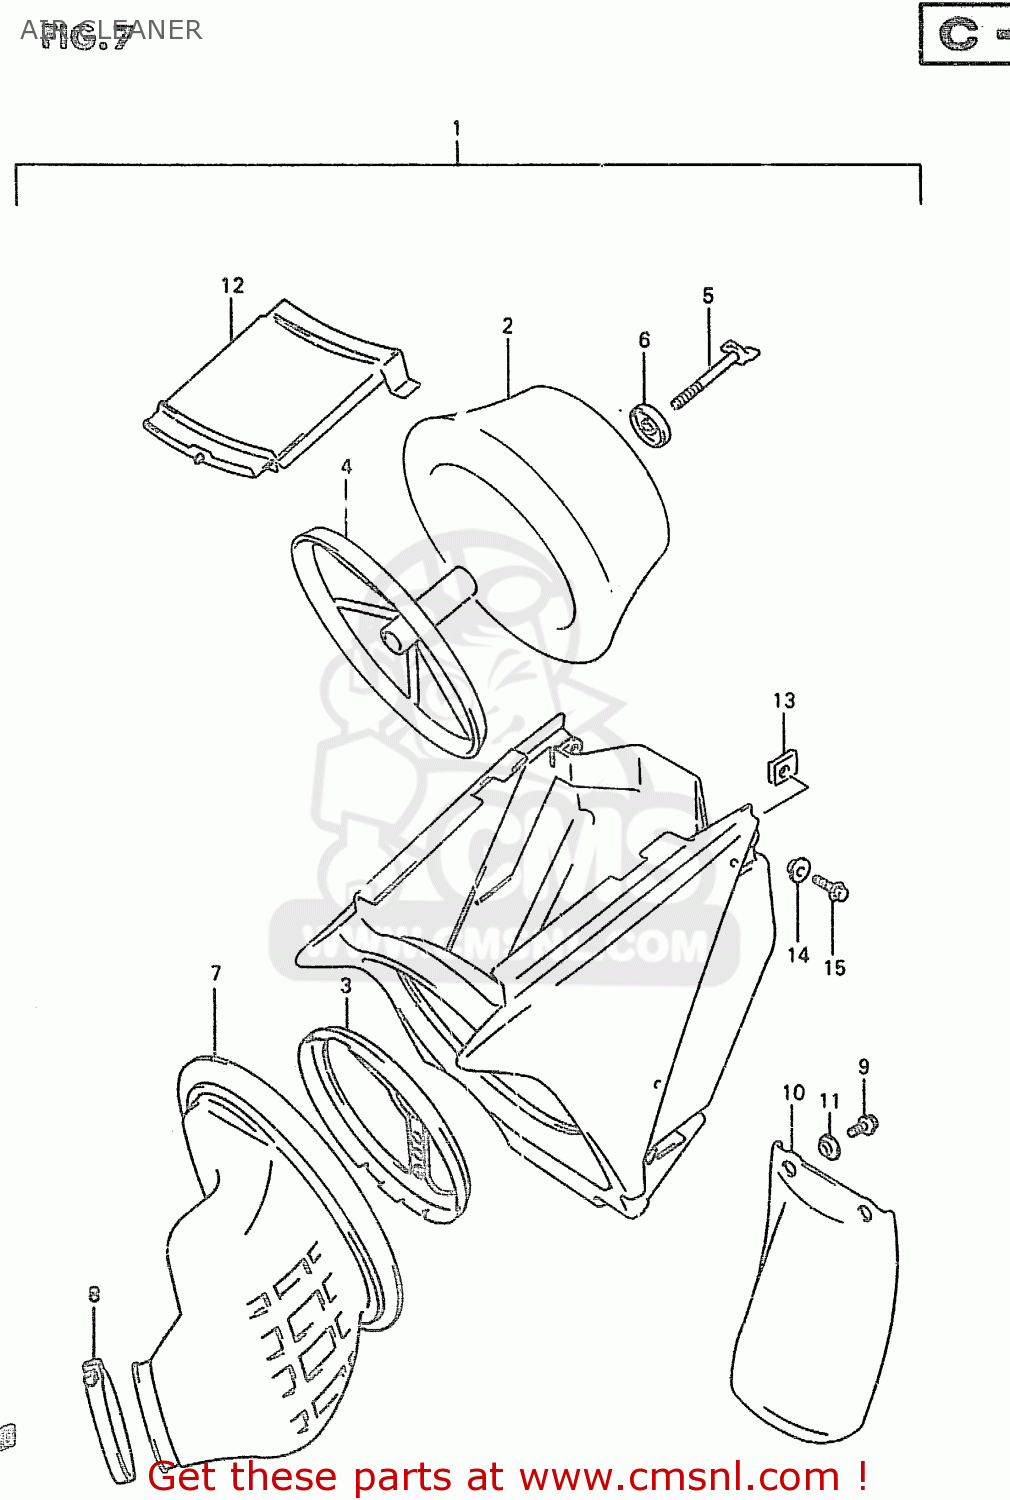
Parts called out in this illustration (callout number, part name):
1	CLEANER ASSY,AIR
2	FILTER ASSY
3	BASE,FILTER
4	HOLDER,FILTER
5	BOLT,WING
6	WASHER,AIR CLEANER
7	TUBE,OUTLET
8	CLAMP
9	BOLT
10	MUDGUARD
11	COLLAR
12	CAP,AIR CLEANER
13	HOLDER,REAR BU
14	WASHER
15	SCREW
